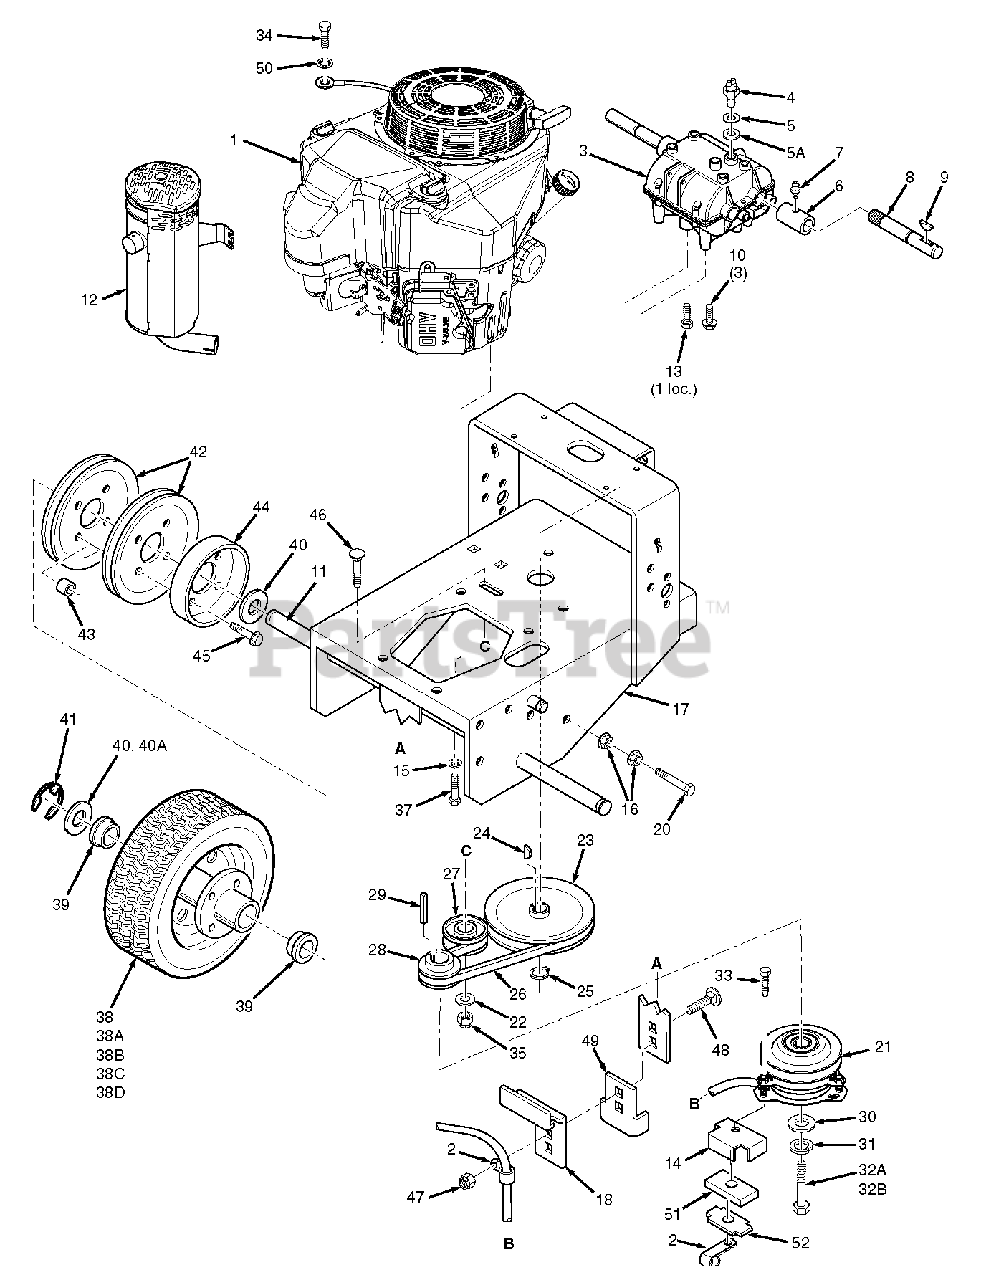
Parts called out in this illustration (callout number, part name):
1	Engine, Kawasaki 14FS (FS481V)
1	Engine, Kawasaki 15FS (FS541V)
2	Cable Clamp
3	Transmission, 5-speed (Peerless 700-070, 9 tooth spline)
4	Neutral Safety Switch
5	Fibre Washer, thin
5A	Fibre Washer, thick
6	Coupler, Jackshaft
7	Grease Fitting, straight 1/4-28
8	Jackshaft (fits SW32,36,48& 52)
9	Key, Hi-Pro #9
10	Bolt, 5/16-18 X 3/4" Hex Head
11	Wheel Axle (SW36,48 & 52)
11	Wheel Axle (SW 32)
12	Muffler - Kawasaki
13	Bolt, 5/16-18 X 3/4" Hex Head
14	Backing Plate
15	Lock Wshr. 3/8"
16	Nut, 3/8-16 Serrated Flange
17	Engine Deck (fits SW32)
17	Engine Deck (fits SW36,48 & 52)
18	Plate, Clutch Bracket
19	Nut, 5/16-18 Serrated Flange
20	Bolt, 3/8-16 x 3-3/4" Hex Head
21	Electric Clutch (Ogura)
22	Washer, 3/8" (.391 x .938 x .105)
23	Pulley, Transmission Input
24	Key, Woodruff #9
25	Retaining Ring, 5/8" Ext, Basic
26	Belt, Transmission Drive
27	Idler Pulley, Transmission
28	Pulley, Traction Drive
29	Key, 1/4 x 1/4 x 3/4"
30	Flat Washer, 7/16" Special
31	Lock Washer, 7/16"
32A	Bolt, 7/16-20 x 2-1/2" Hex Head
32B	Cpsrw, M10-1.5 x55 Metric Hex Hd
33	Bolt, 5/16-18 x 1-3/4" Hex Head
34	Bolt, M8-1.25 x 16
35	Nut, 3/8-16 Elastic Stop
36	Flat Washer, 5/16"
37	Bolt, Hex Head 3/8-16 x 1-1/4"
38	Wheel Assembly (fits SW36,48,52)
38	Wheel Assembly (SW32)
38A	Tire, 13 x 6.50-6, 2-ply (fits SW36,48,52)
38B	Rim & Bearing Assembly
38C	Tire, 13 x 5.00-6 2-ply (SW32 only)
38D	Rim Assembly (SW32 only)
39	Wheel Bearing
40	Washer, 1-1/16 x 1-3/4 x 12 ga
40A	Washer, 1-1/16 x 1-1/2 x 18 ga
41	Retaining Ring, 1" Ext.- "E"
42	Pulley, Wheel Drive
43	Spacer, Wheel Pulley
44	Brake Drum
45	Bolt, 5/16-18 x 1-1/2" Serrated Flange
46	Bolt, 3/8-16 x 2" Carriage
47	Nut, 5/16-18 Elastic Stop
48	Bolt, 5/16-18 x 1" Carriage
49	Anti Rotation Bracket
50	Lock Washer External Tooth
51	Rubber Pad, Clutch Stop
52	Plate, Backing
